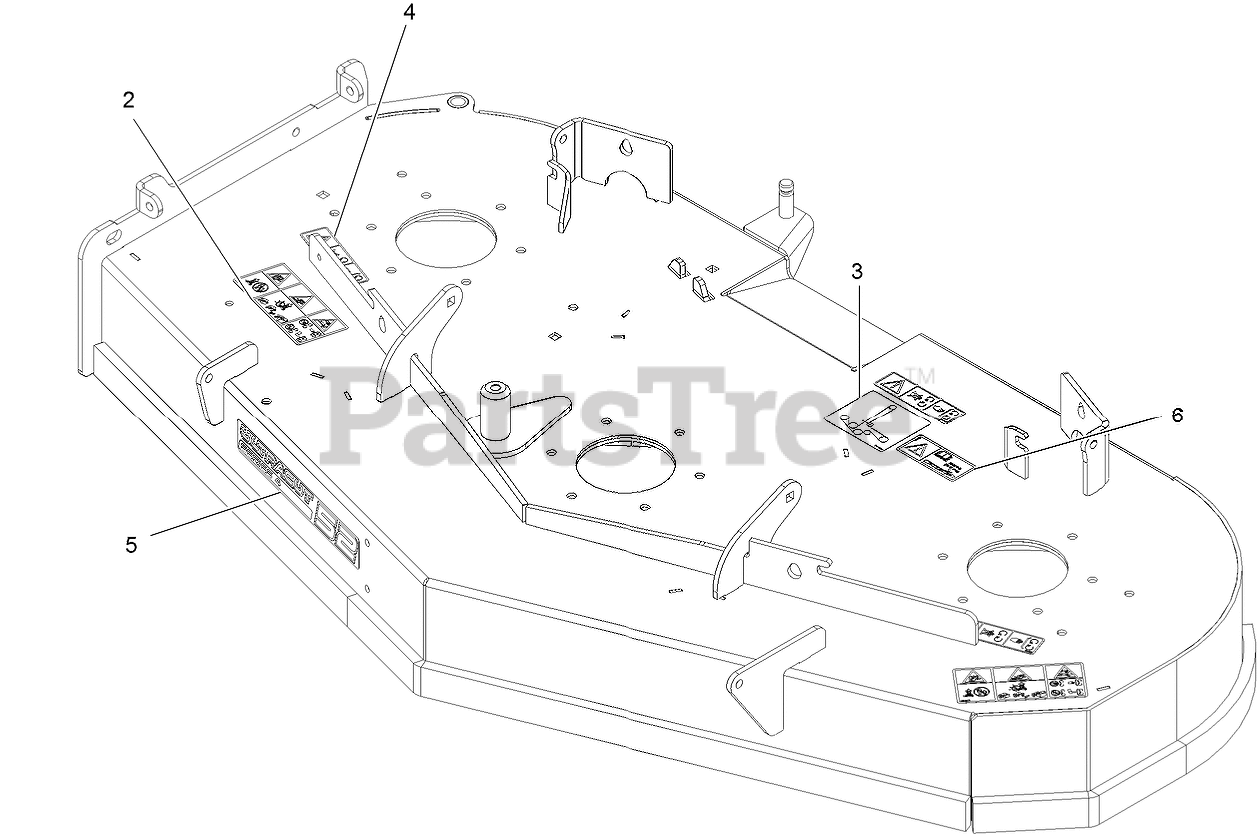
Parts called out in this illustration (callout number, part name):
2	DECAL-WARNING THROWN OBJ
3	DECAL-BELT ROUTING
4	DECAL-COVER, MISSING
5	DECAL, 524
6	DECAL-TORQUE, BOLT
